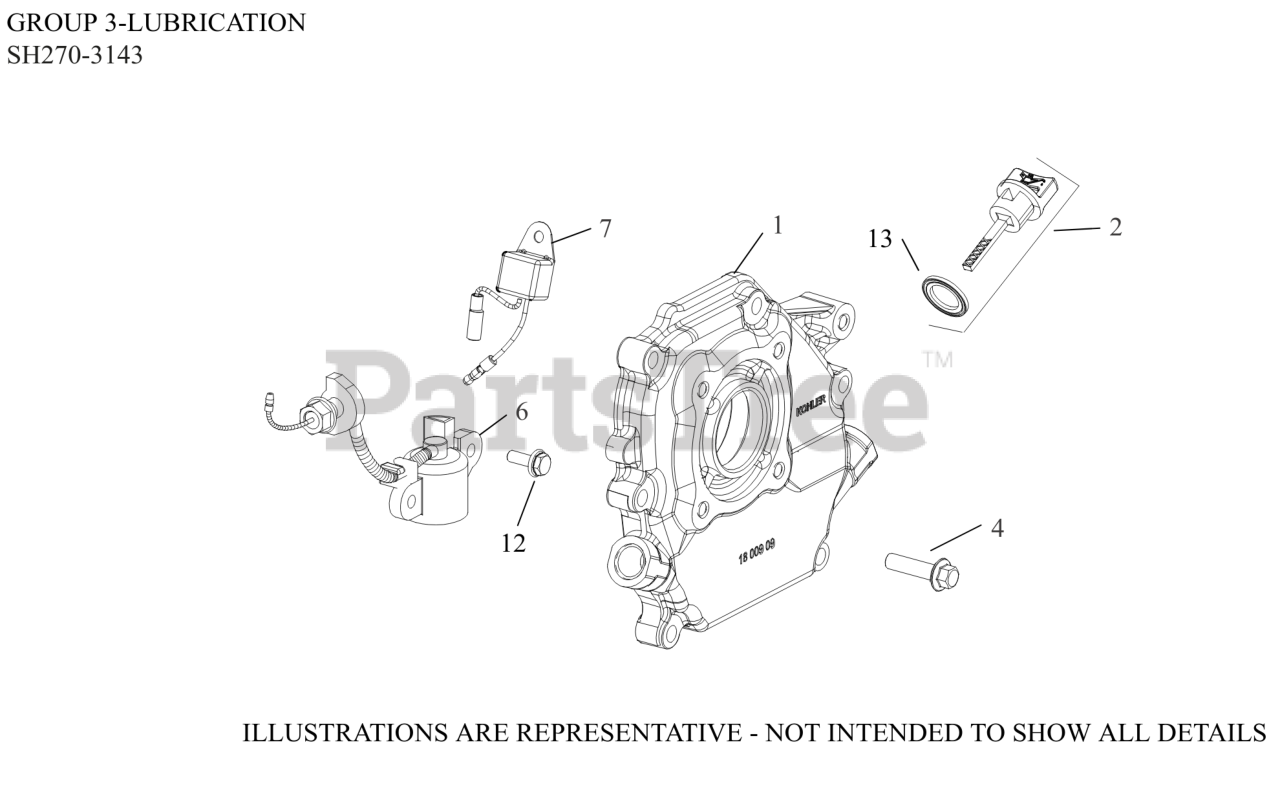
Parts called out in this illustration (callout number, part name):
1	PLATE, CLOSURE & BEARING
2	DIPSTICK ASSEMBLY
4	SCREW, CLOSURE PLATE
6	SWITCH, OIL SENSOR ASSEMBLY
7	CONTROL, OIL ALERT UNIT
12	SCREW, M6 X 16
13	GASKET, DIPSTICK
